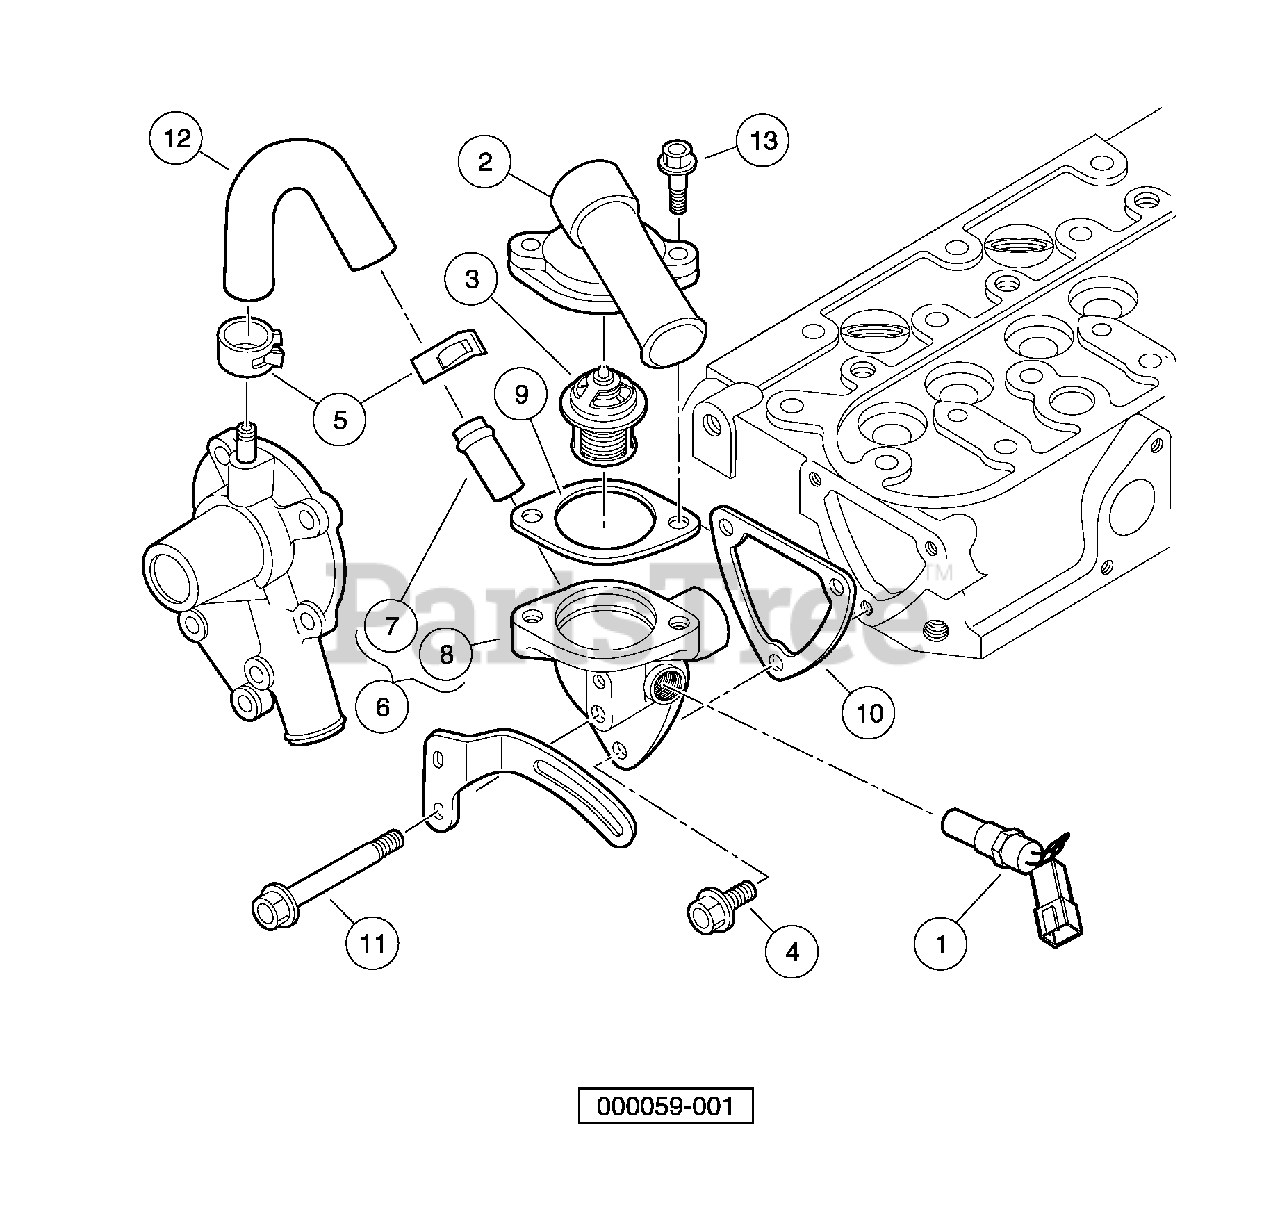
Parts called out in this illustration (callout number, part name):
1	Sensor, Coolant Temp
2	Cover, Thermostat
3	Assy, Thermostat
4	Bolt, M6 X 1 X 20
5	Band, Pipe
6	Flange, Water
7	Pipe, Water Return, D722
8	Flange, Water
9	Gasket, Thermostat
10	Gasket, Water Flange
11	Bolt, Alt, D722, Stay Lower
12	Pipe, Water Return, D722
13	Bolt, D722, Thermostat Cover
